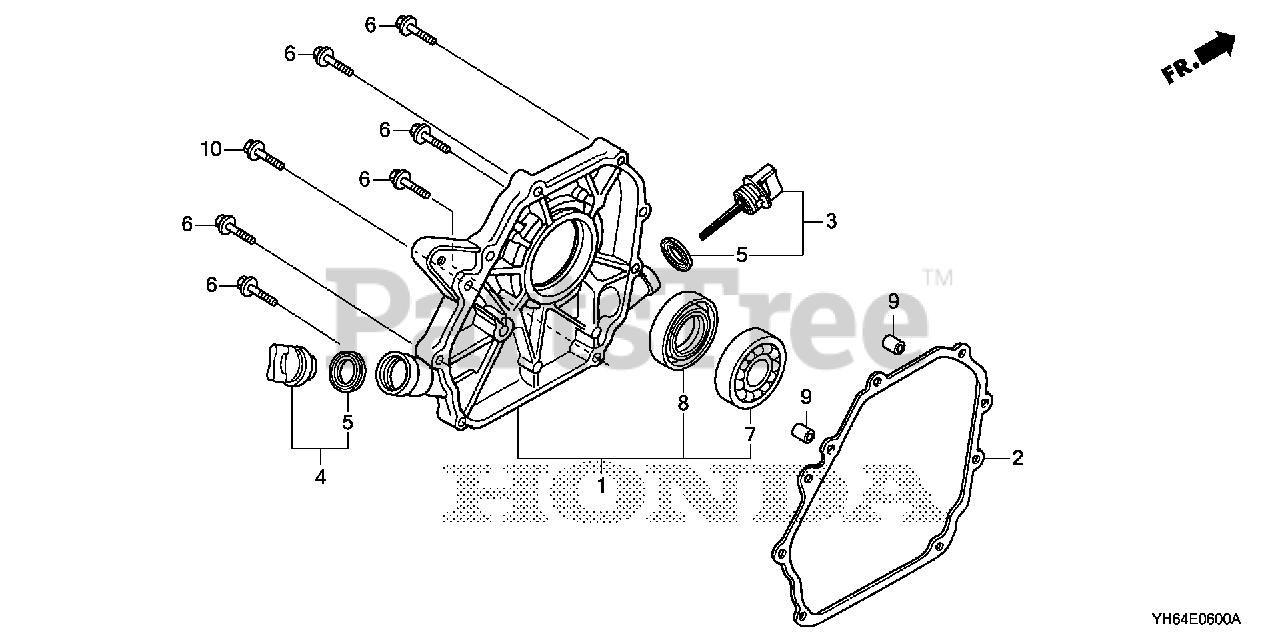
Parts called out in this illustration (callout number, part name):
1	COVER ASSY., CRANKCASE
2	GASKET, CASE COVER
3	CAP ASSY., OIL FILLER
4	CAP ASSY., OIL FILLER
5	GASKET, OIL FILLER CAP
6	BOLT, FLANGE (6X28) (CT200) Use up to Engine SN 1530314.
7	BEARING, RADIAL BALL (62/22)
8	OIL SEAL (22X41X6)
9	PIN A, DOWEL (8X14)
10	BOLT, FLANGE (6X28) (CT200) Use up to Engine SN 1530314.
